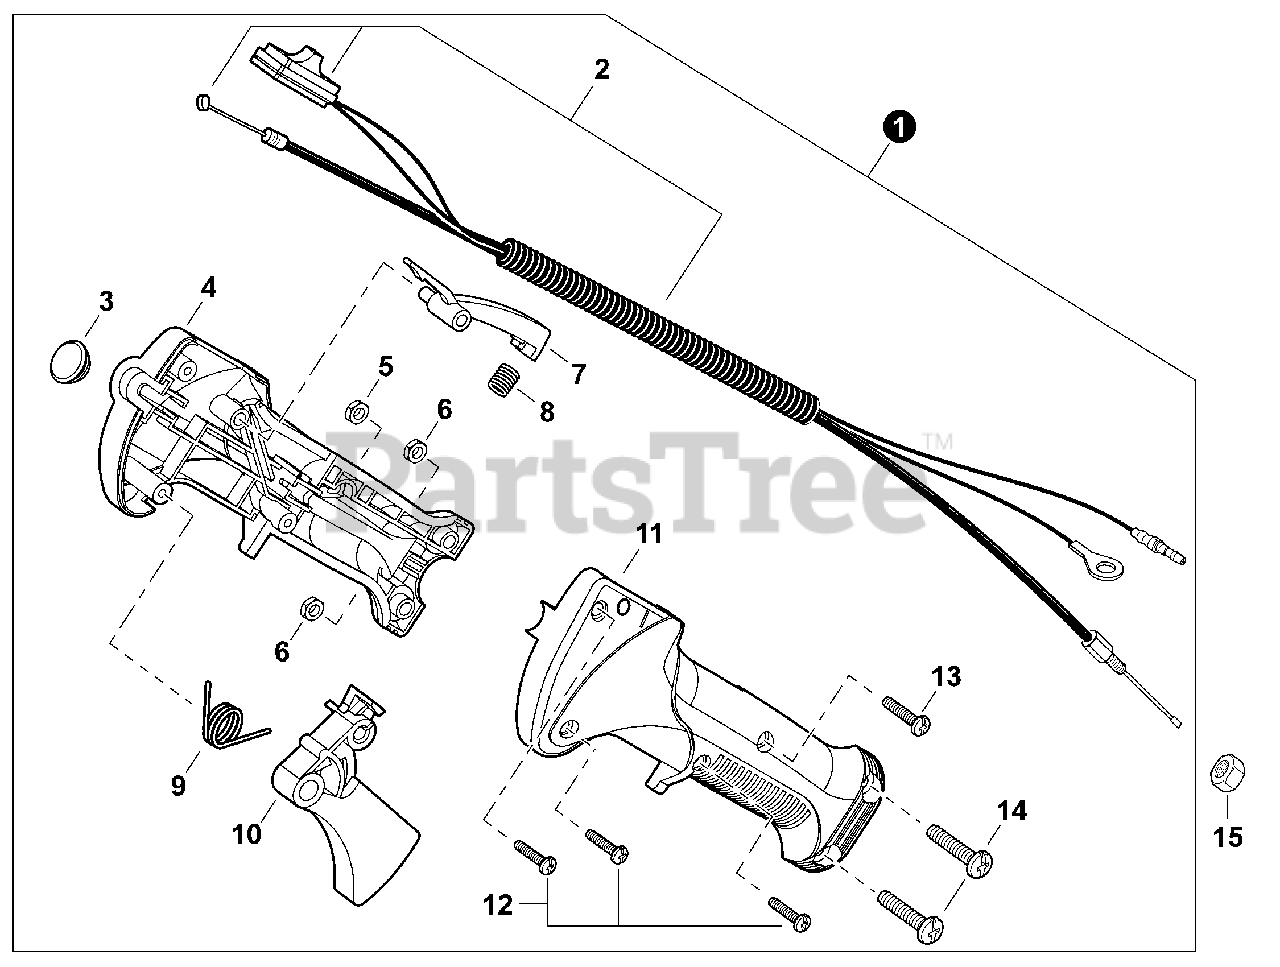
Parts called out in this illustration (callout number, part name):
1	THROTTLE CONTROL ASSY
2	CABLE ASSY, CONTROL
3	PLUG, RUBBER
4	CONTROL HANDLE - RIGHT
7	LOCKOUT, THROTTLE
8	SPRING, COMPRESSION
9	SPRING, TORSION
10	TRIGGER, THROTTLE
11	CONTROL HANDLE - LEFT
12	SCREW, TAPPING 4×16
13	SCREW M4×23
14	SCREW M5×22
